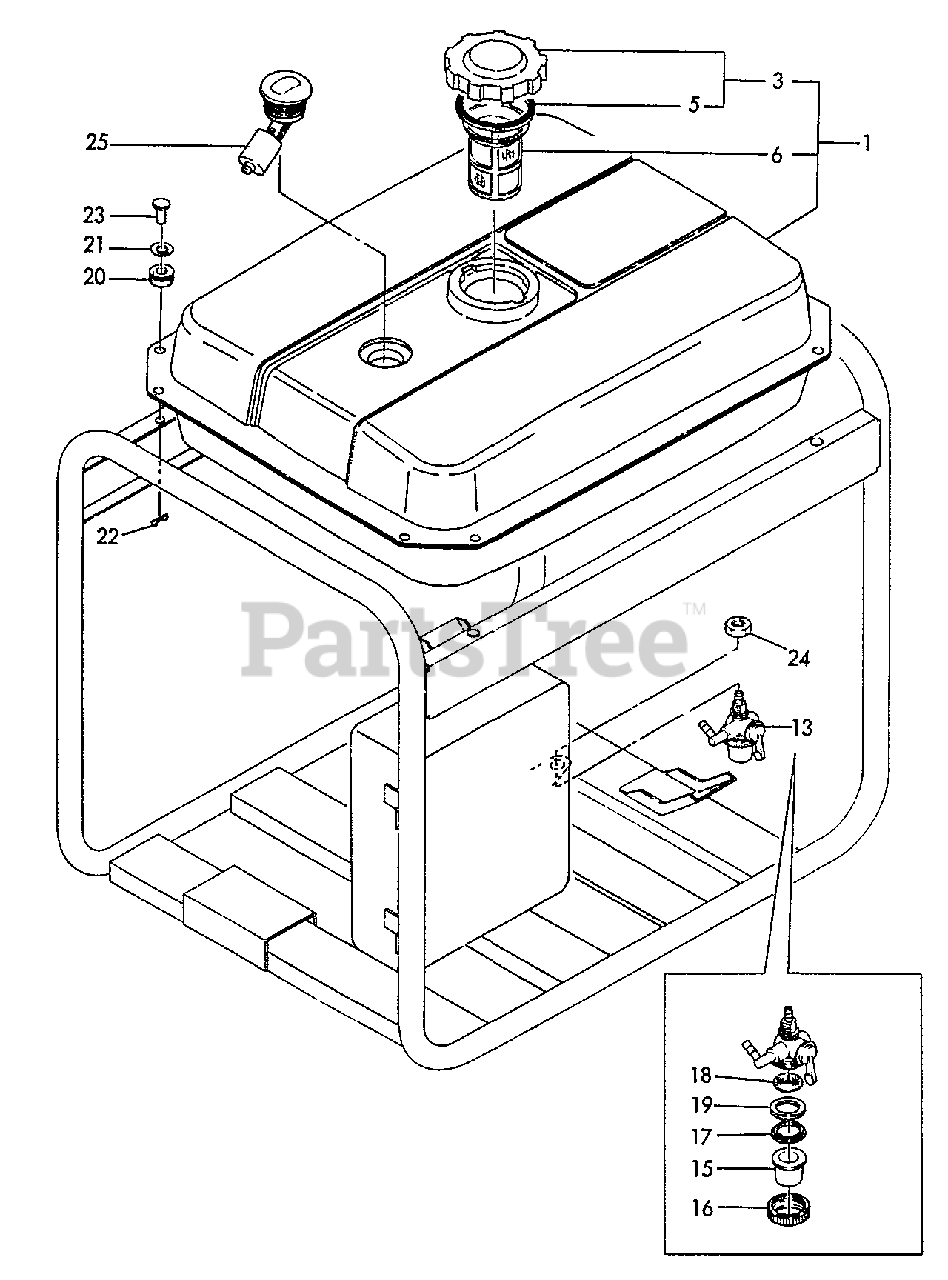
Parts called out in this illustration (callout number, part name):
1	FUEL TANK ASSY
3	CAP ASSY
5	GASKET
6	STRAINER, FUEL
13	FUEL COCK ASSY
15	BOWL, STRAINER
16	RETAINER
17	GASKET
18	FILTER, FUEL
19	PLATE
20	GROMMET
21	WASHER
22	PIN - 6 -- SNAP
23	PIN - 6X14
24	LOCKNUT - 12
25	GAUGE, FUEL
